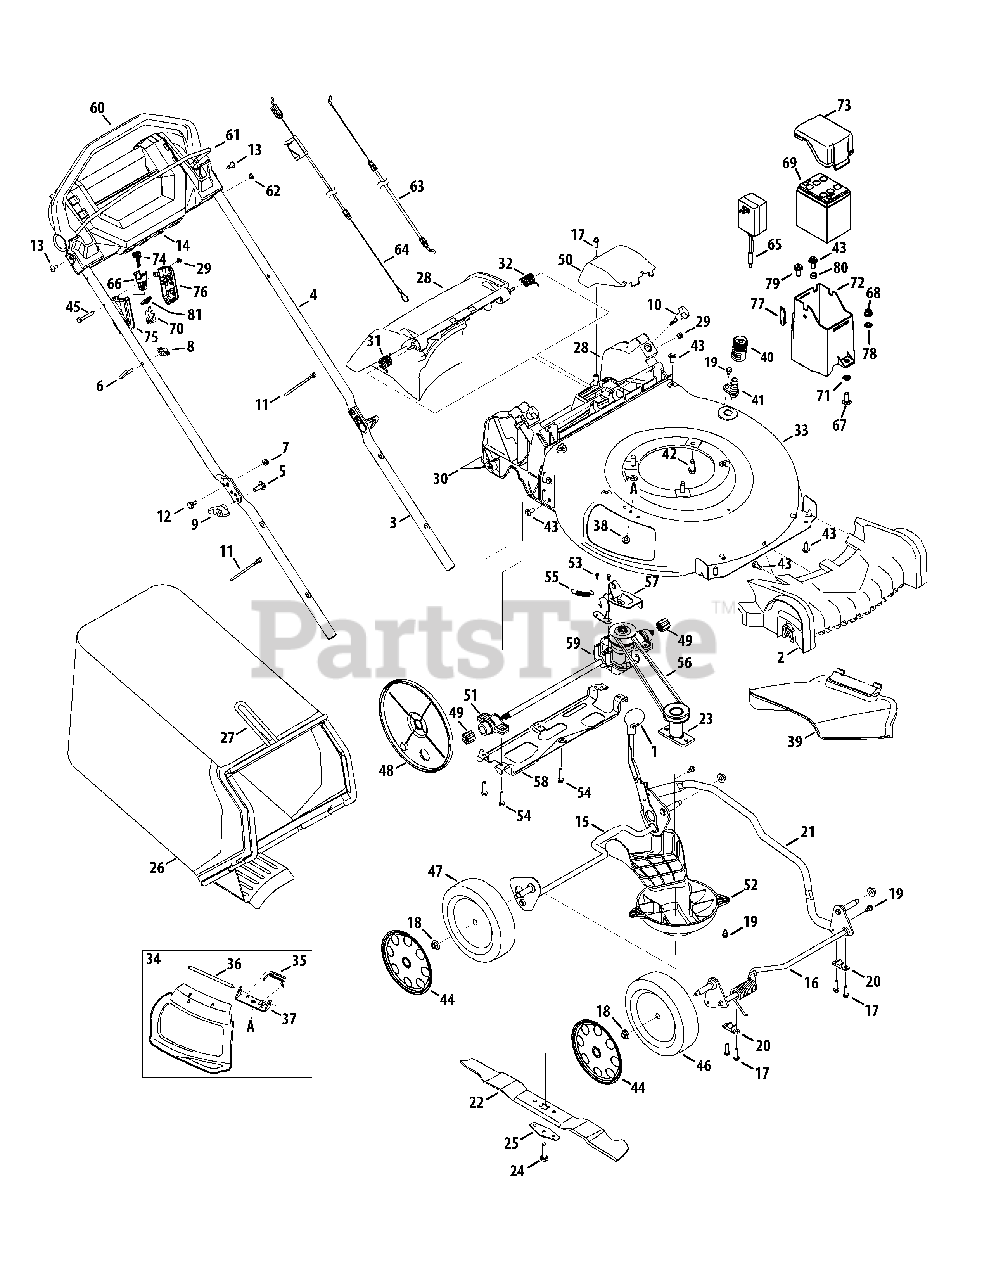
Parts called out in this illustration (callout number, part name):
1	Adjustment Lever Knob
2	Front Cover
3	Lower Handle
4	Upper Handle
5	Carriage Screw ,5/16-18
6	Rope Guide
7	Nut, Flange Lock, 1/4-20
10	Wing Nut
11	Cable Tie
12	Sldr. Screw, .375 x .126 x 1/4-20
13	Screw, 1/4-14 x .625
14	Handle Console
15	Rear Axle Assembly
16	Front Axle Assembly
17	Screw, 1/4-15 x .750
18	Flange Lock Nut, 3/8-16
19	Scr., Shldr., 1/4-20 x .50
20	Bushing, Lock, .505 Dia. X .62
22	Mulching Blade
23	Blade Adapter
24	Screw, 3/8-24 x 1.50
25	Blade Bell Support
27	Grass Catcher Frame
28	Rear Discharge Door Assembly
29	Nut, Sq., 1/4-20
30	Trailing Shield
31	Torsion Spring - RH
32	Torsion Spring - LH
34	Mulch Plug (Incl. 35-37)
35	Torsion Spring
37	Chute Deflector Bracket
38	Screw, 1/4-20 x .500
39	Side Discharge Chute
40	Water Nozzle Adapter
41	Water Nozzle
42	Screw, 3/8-16 x 1.00
43	Screw, 5/16-14 x .750
44	Hubcap, 8"
45	Screw, 1/4-20 x 1.75
46	Front Wheel
47	Rear Wheel
48	Wheel Dust Cover
49	Spur Gear, 10T
50	Transmission Cover
51	Bearing Assembly
52	Engine Baffle
53	Screw, Hex Washer, .159 x .43
54	Screw, 1/4-15 x 1.25
55	Exten. Spring, 2.405
57	Transmission Bracket
58	Rear Support Bracket
59	Transmission Assembly
60	Drive Handle
61	Blade Control
62	Shoulder Spacer, .18 x .315 x .09
63	Control Cable
64	Drive Cable
65	Battery Charger
67	Bolt, Carr., 5/16-18 x 1.00
68	Nut, Flglk., 5/16-18
69	Battery
70	Plunger Switch
71	Speed Nut
72	Battery Housing
73	Battery Housing Top
75	Electric Start Housing, RH
76	Electric Start Housing, LH
77	Lid Seal
78	Washer, Bell, .340 x .872 x .080
79	Scr., Sldr., 5/16-14 x .972
80	Spacer, .340 x .460 x .246
81	Retainer Bracket
